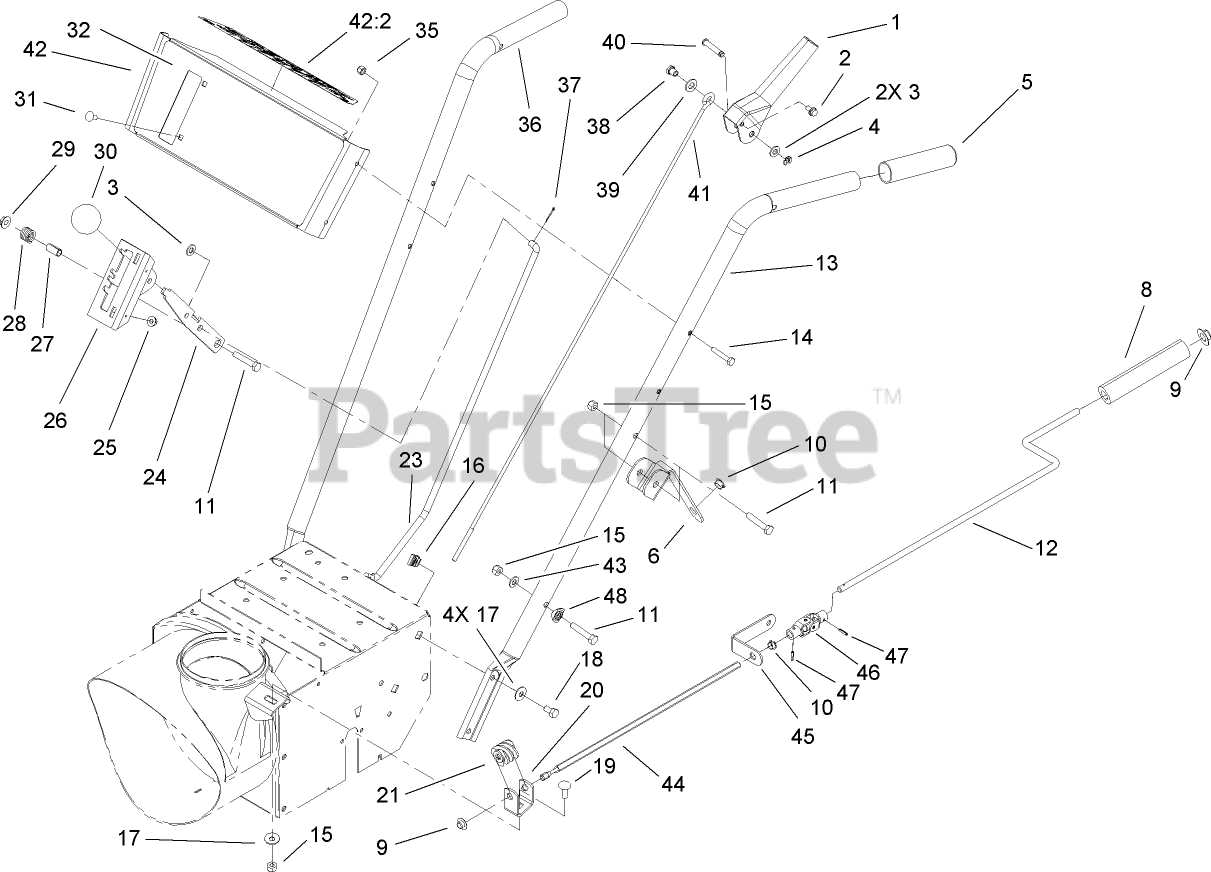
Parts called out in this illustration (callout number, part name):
1	HANDLE-CONTROL
2	SCREW-HHF
3	WASHER-PLAIN
4	RING-CLIP
5	GRIP-HANDLE
6	BRACKET-ROD, UPPER CHUTE
8	GRIP-CONTROL, CHUTE
9	NUT-PUSH
11	SCREW-HH
12	ROD-CHUTE, UPPER
13	HANDLE-LEFT
14	SCREW-HH
15	NUT-LOCK, NI
17	WASHER-BELLEVILLE
18	SCREW-HH
19	SCREW-CARR
20	BRACKET-WORM
21	GEAR-WORM, CHUTE
23	ROD-SELECTOR, SPEED
24	SELECTOR-SPEED
25	NUT-HF
26	MOUNT-SELECTOR, SPEED
27	SPACER
28	SPRING
29	NUT-HF
31	SCREW-CARR
32	DECAL-ESCUTCHEON
35	NUT-LOCK, NI
36	HANDLE-RIGHT
37	PIN-COTTER
38	POST-MOUNTING, LINKAGE
39	WASHER-FLAT
40	PIN-LEVER, CONTROL
41	LINK-UPPER
42	ESCUTCHEON PANEL ASM
42:2	DECAL-ESCUTCHEON, BACK
43	WASHER-PLAIN
44	ROD-CHUTE, LOWER
45	BRACKET-ROD, LOWER
46	JOINT-UNIVERSAL
47	PIN-ROLL
48	WASHER
